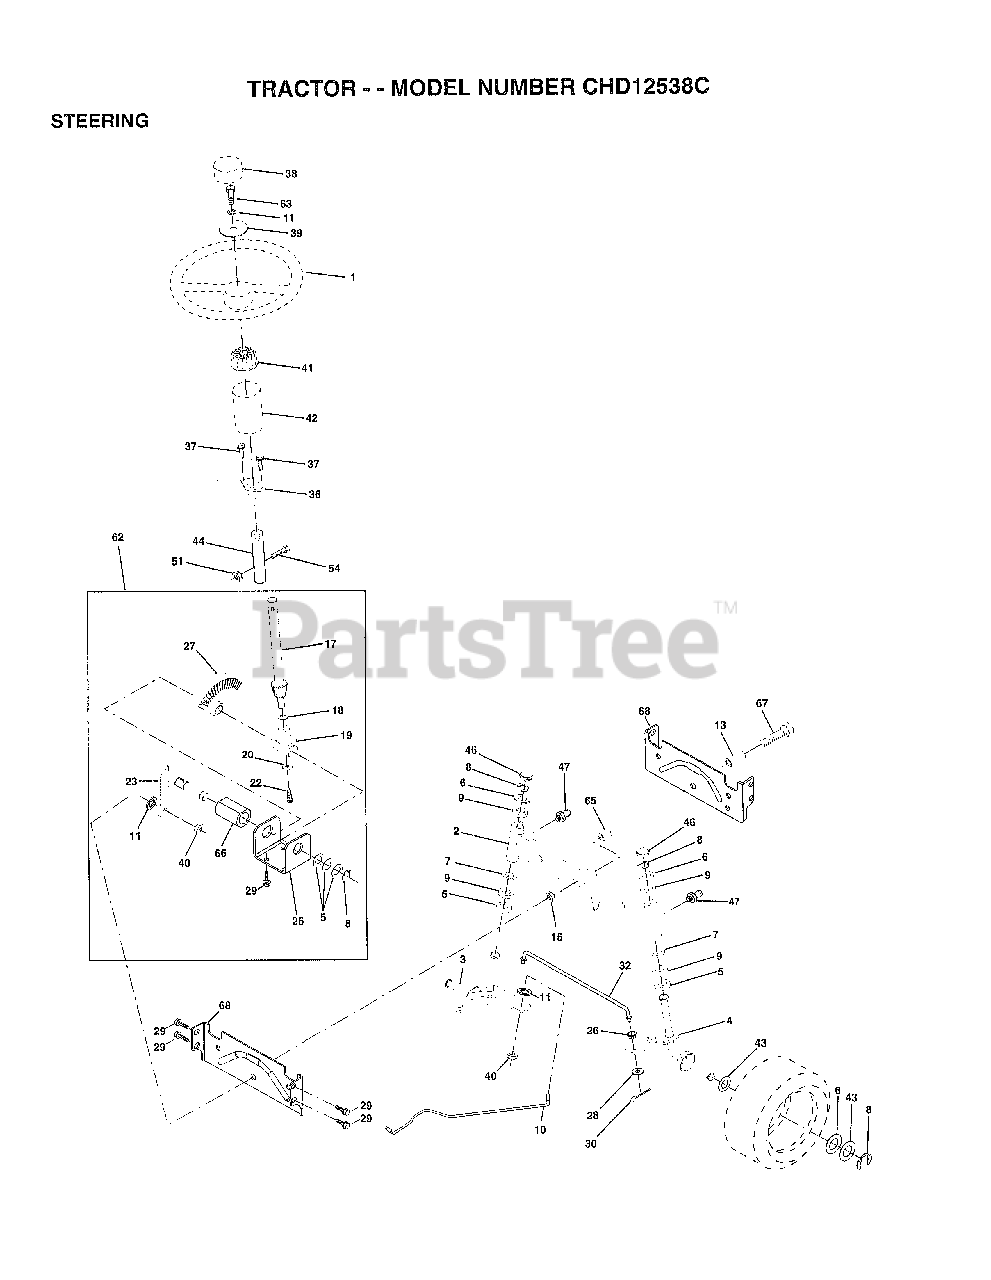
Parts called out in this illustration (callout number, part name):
1	WHEEL STR AYP BLK
2	AXLE ASM
3	SPINDLE.ASM.LH
4	"SPINDLE ASM,RH"
5	WASHER .T
6	WASHER
7	WASHER
8	RING
9	COL. SRTG. BEAR.
10	DRAGLINK-STAMPED
11	LOCKWASHER
13	BEARING AXLE
15	"NUT-LOC,FLANGE LT"
17	SHAFT ASM STEERIN
18	THRUST WASHER
19	SUPPORT.SHAFT
22	SCREW HEX SOC1/4-
25	BRKT-STEERING
26	BUSHING.DRAGLINK
27	GEAR SECTOR
28	WASHER
29	SCREW
30	COTTER PIN
32	TIE ROD
36	BUSHING.STEERING
37	"SCREW-TT,10-32 FL"
38	CAP STEER AYP
39	WASHER T
40	GRIPCO NUT
41	ADAPTER LT
42	BOOT.STEER.PL
44	EXT SHAFT STEERIN
46	CAP
47	ZERK M
51	NUT
54	BOLT
62	KIT STEERING ASM
63	BOLT
65	SPACER AXLE
66	"BEARING-ARM,PITMA"
67	BOLT
68	BRACE AXLE
